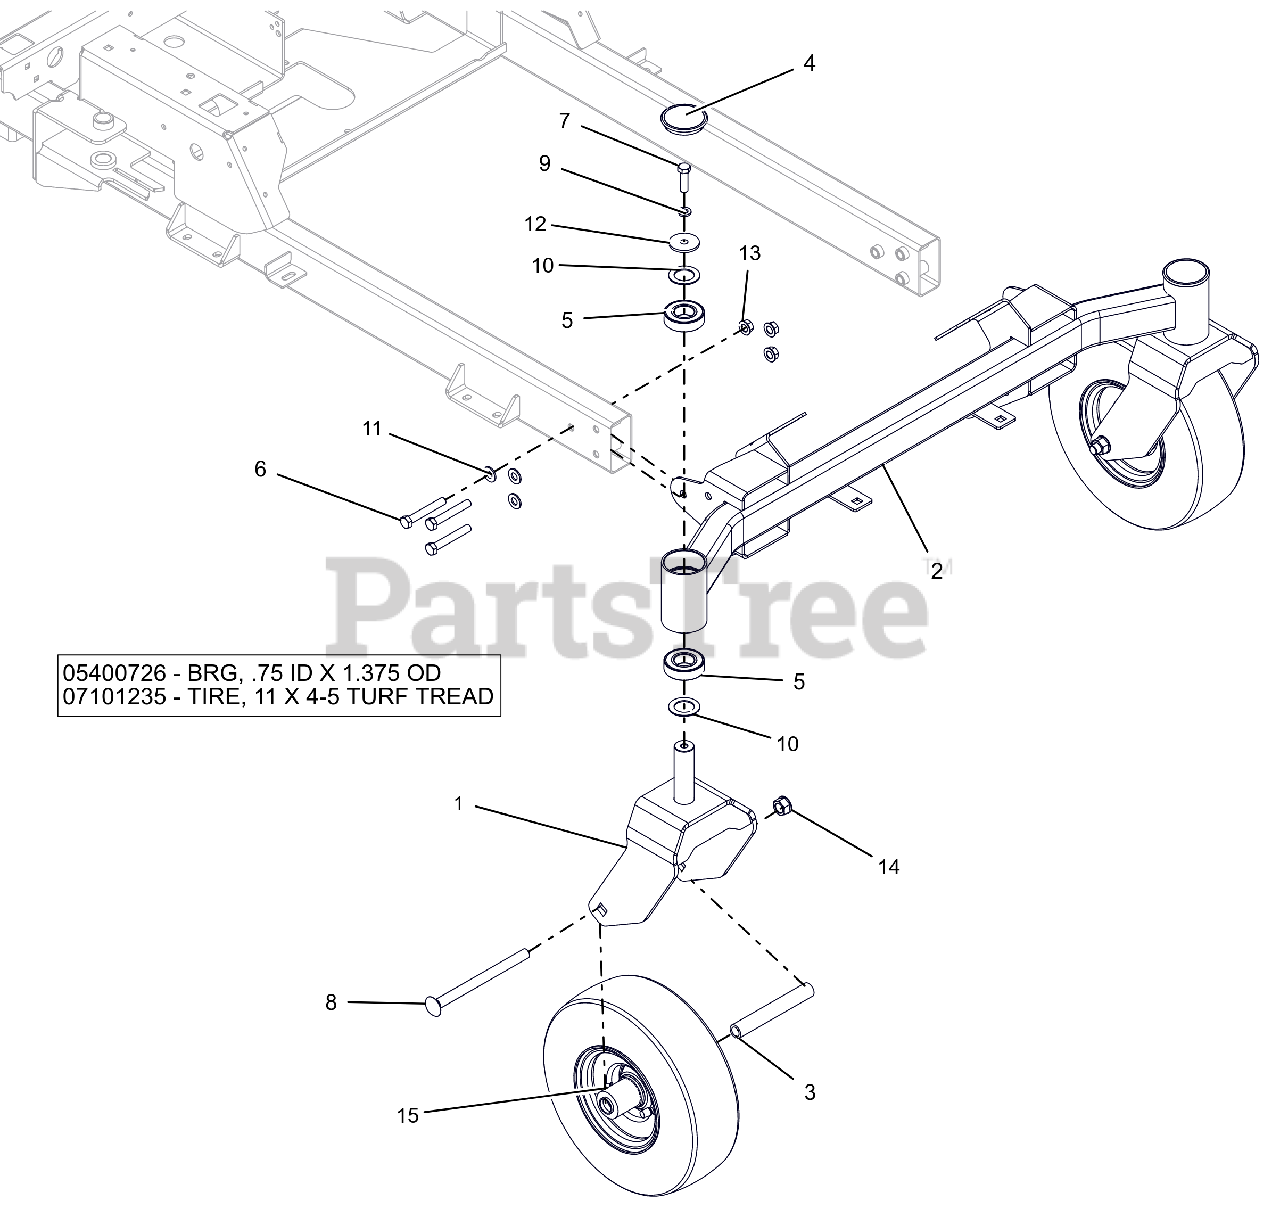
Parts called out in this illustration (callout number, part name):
1	WMT, CASTER FORK
2	WLDMT, AXLE FRONT
3	SPACER, ROLLED WHEEL
4	CAP, DUST
5	BRG,BALL 1.00X2.00X.563(1641)
6	BLT-HEX .38-16X2.50 GR8 YWZC
7	@BLT-HEX .38-16X1.25 GR5 YWZC
8	BLT-RDHDSQNK .50-13X6.50 GR5 Y
9	@WSHR-LK .38X.094 REG YWZC
10	WSHR-HRD-THRS 1.007X1.542X.062
11	WSHR-HDND .406X.812X.055
12	WSHR-FL-STL .380X1.50X.125YWZC
13	NUT-LK-TOP-FLG .38-16 GRG YWZC
14	@NUT-LK-TOP-FLG .50-13 YWZC
15	ASM, WHL/TIRE 11X4.00-5
15	BRG, .75 ID X 1.375 OD
15	LAWN TIRE FRONT, 11/4-5 TURF TREAD
